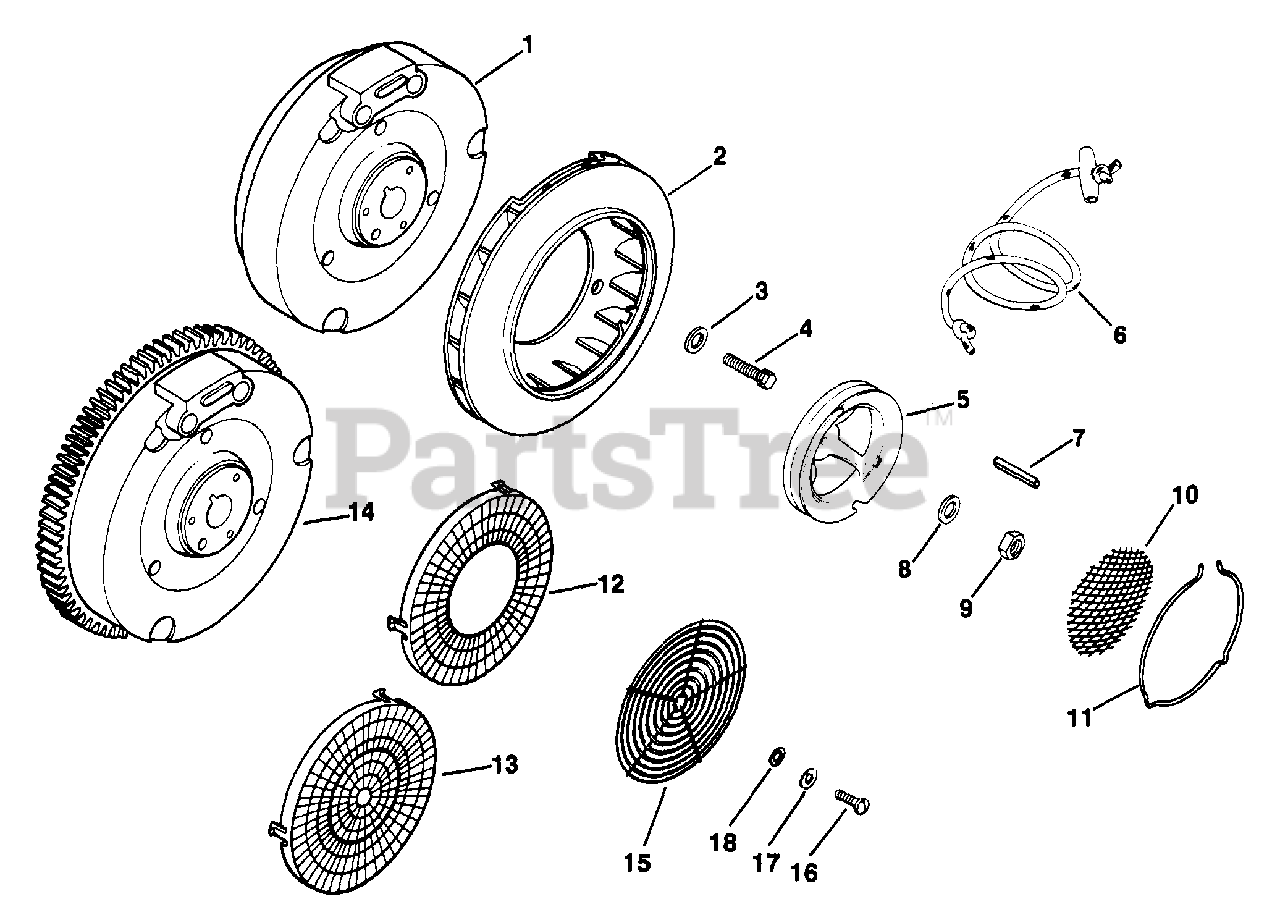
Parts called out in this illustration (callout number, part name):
2	FAN - USE 41 157 01-S
3	SPACER - USE 25 431 01-S
4	SCREW - USE 25 086 14-S
7	KEY - USE X-286-17-S
8	WASHER - USE X-25-15-S
9	NUT - USE 25 100 02-S
12	SCREEN
14	FLYWHEEL - USE 41 025 48-S
